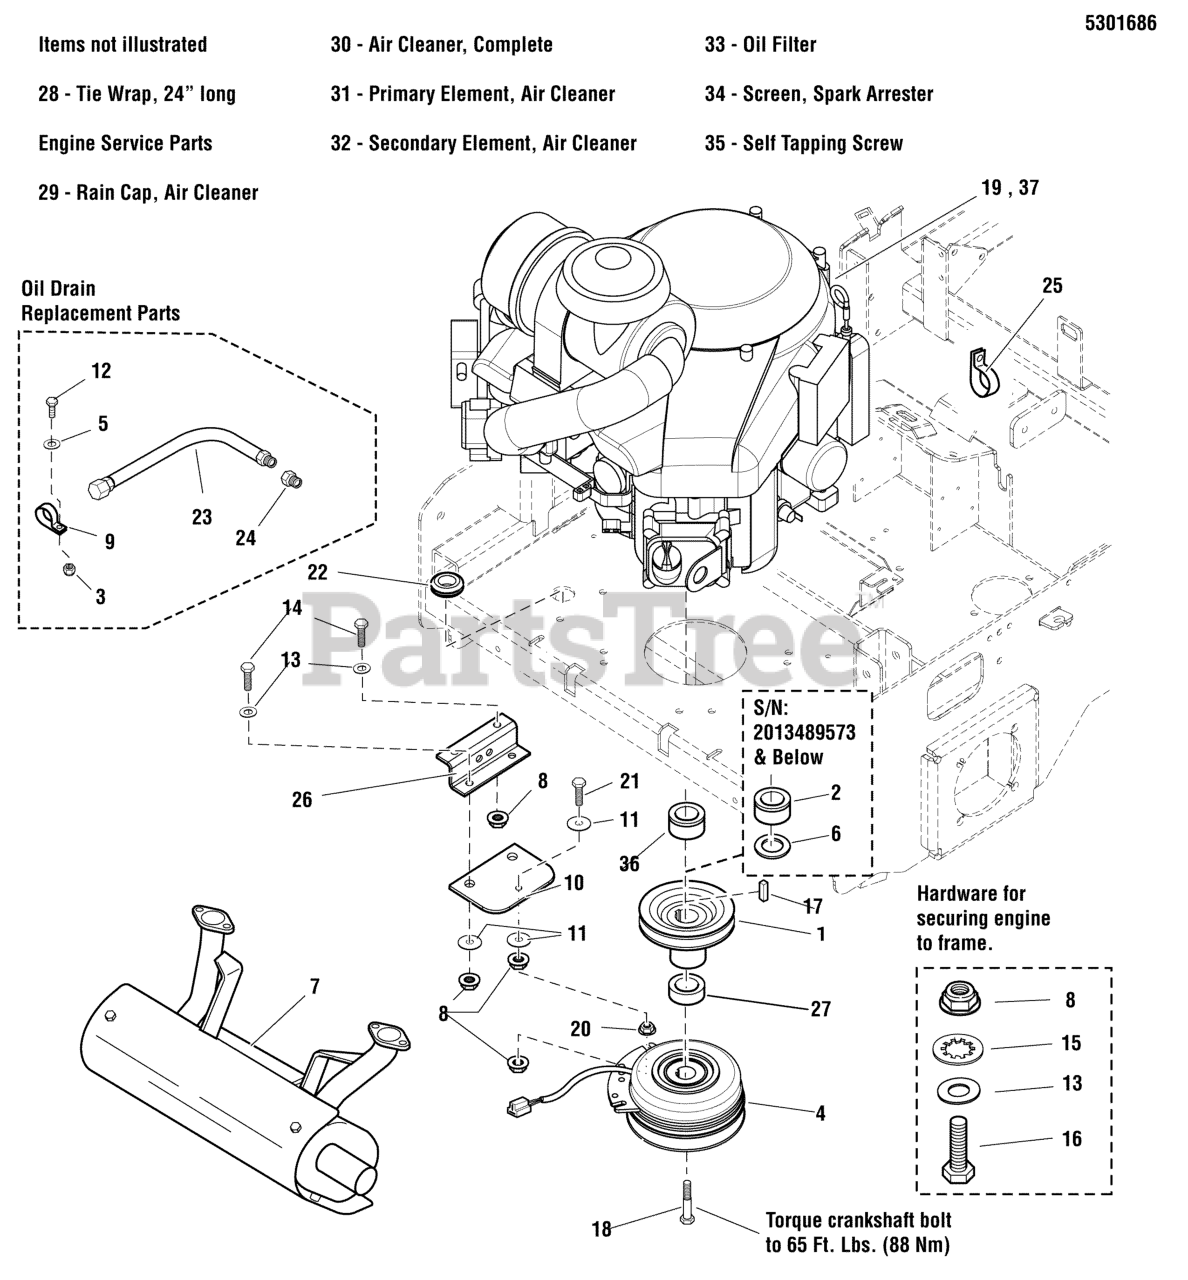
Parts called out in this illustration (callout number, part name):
1	PULLEY, 5.15 OD X 1-1/8 BORE B-SECT
2	SPACER, 1.13 X 1.75 X .97
3	NUT, 1/4-20 HEX NYLOCK FLANGE
4	* CLUTCH, 5218-134, WARNER
5	WASHER, 1/4 SAE
6	SPACER, 1.13 X 2.00 X .19
7	MUFFLER ASSY, SERVICE PART
8	NUT, 5/16-18 HEX NYLOCK FLANGE
9	CLAMP, VINYL INSULATED
10	CLUTCH ANCHOR PAD
11	WASHER, 5/16 FENDER
12	BOLT, 1/4-20 X 1-3/4 GD5 YZ
13	WASHER, 5/16" SAE
14	BOLT, 5/16-18 X 1 GD5 YZ
15	WASHER, 5/16 INT. TOOTH LOCK
16	BOLT, 5/16-18 X 1-3/4 GD5 YZ
17	KEY, 1/4 SQ X 1
18	BOLT, CRANKSHAFT, 7/16X2-1/2
20	NUT, 5/16-18 HEX SERRATED FLANGE (LARGE)
21	BOLT, 5/16-18 X 2-1/4 TFL, GD5 YZ
22	GROMMET, 7/8
23	HOSE, OIL DRAIN
24	METRIC ADAPTER, M14-1.5" TO 3/8 NPTF
25	CLAMP, HOSE, 1.000 DIA.
26	ANCHOR, CLUTCH - BLK
27	SPACER, 1.13 X 1.75 X .62
36	SPACER, 1.13 X 1.75 X 1.194, YZ
38	TIE,SELF-LOCKING, 24"
